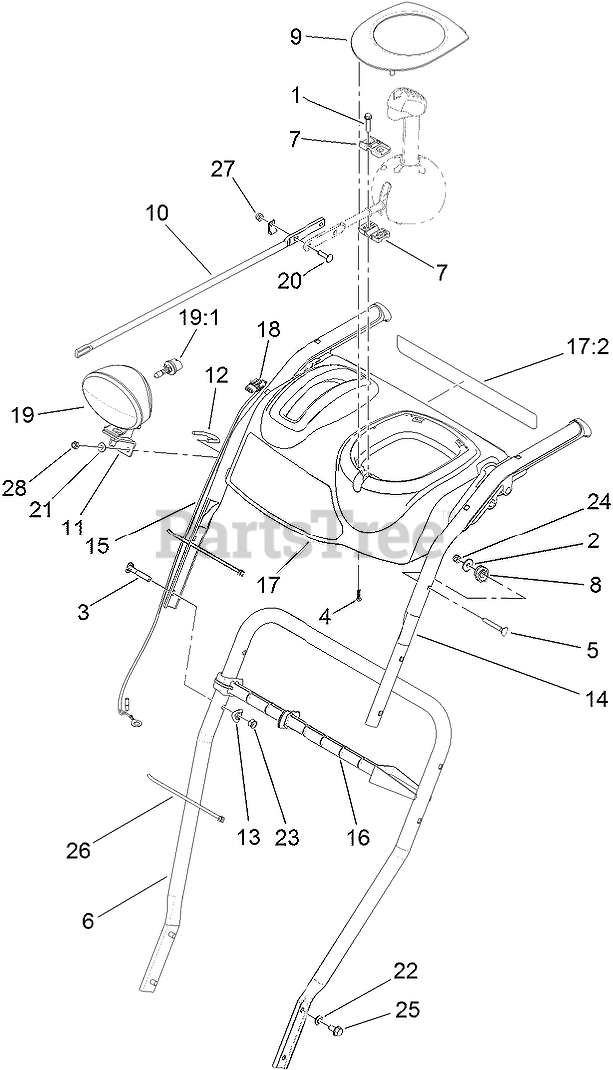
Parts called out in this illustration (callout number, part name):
1	SCREW-PLASTITE
2	WASHER-PLAIN
3	SCREW-HANDLE
4	SCREW-PPH
5	SCREW
6	HANDLE-LOWER
7	SUPPORT-ROD
8	CLAMP-CABLE
9	COVER-PANEL, CONTROL
10	ROD-CHUTE, FRONT
11	BRACKET-LIGHT
12	CLAMP
13	WASHER
14	HANDLE-UPPER, LH
15	HANDLE-UPPER, RH
16	STICK-CLEANOUT
17	PANEL-CONTROL
17:2	DECAL-WARNING
18	HARNESS-WIRE, HEADLIGHT
19	HEADLAMP ASM
19:1	LAMP-12 VOLT
20	SCREW-CARR
21	WASHER-FLAT
22	WASHER-BELLEVILLE
23	NUT-LOCK, NI
24	NUT-LOCK, NI
25	SCREW-HWHTF
26	TIE-CABLE
27	NUT-LOCK, NI
28	NUT-LOCK, NI
